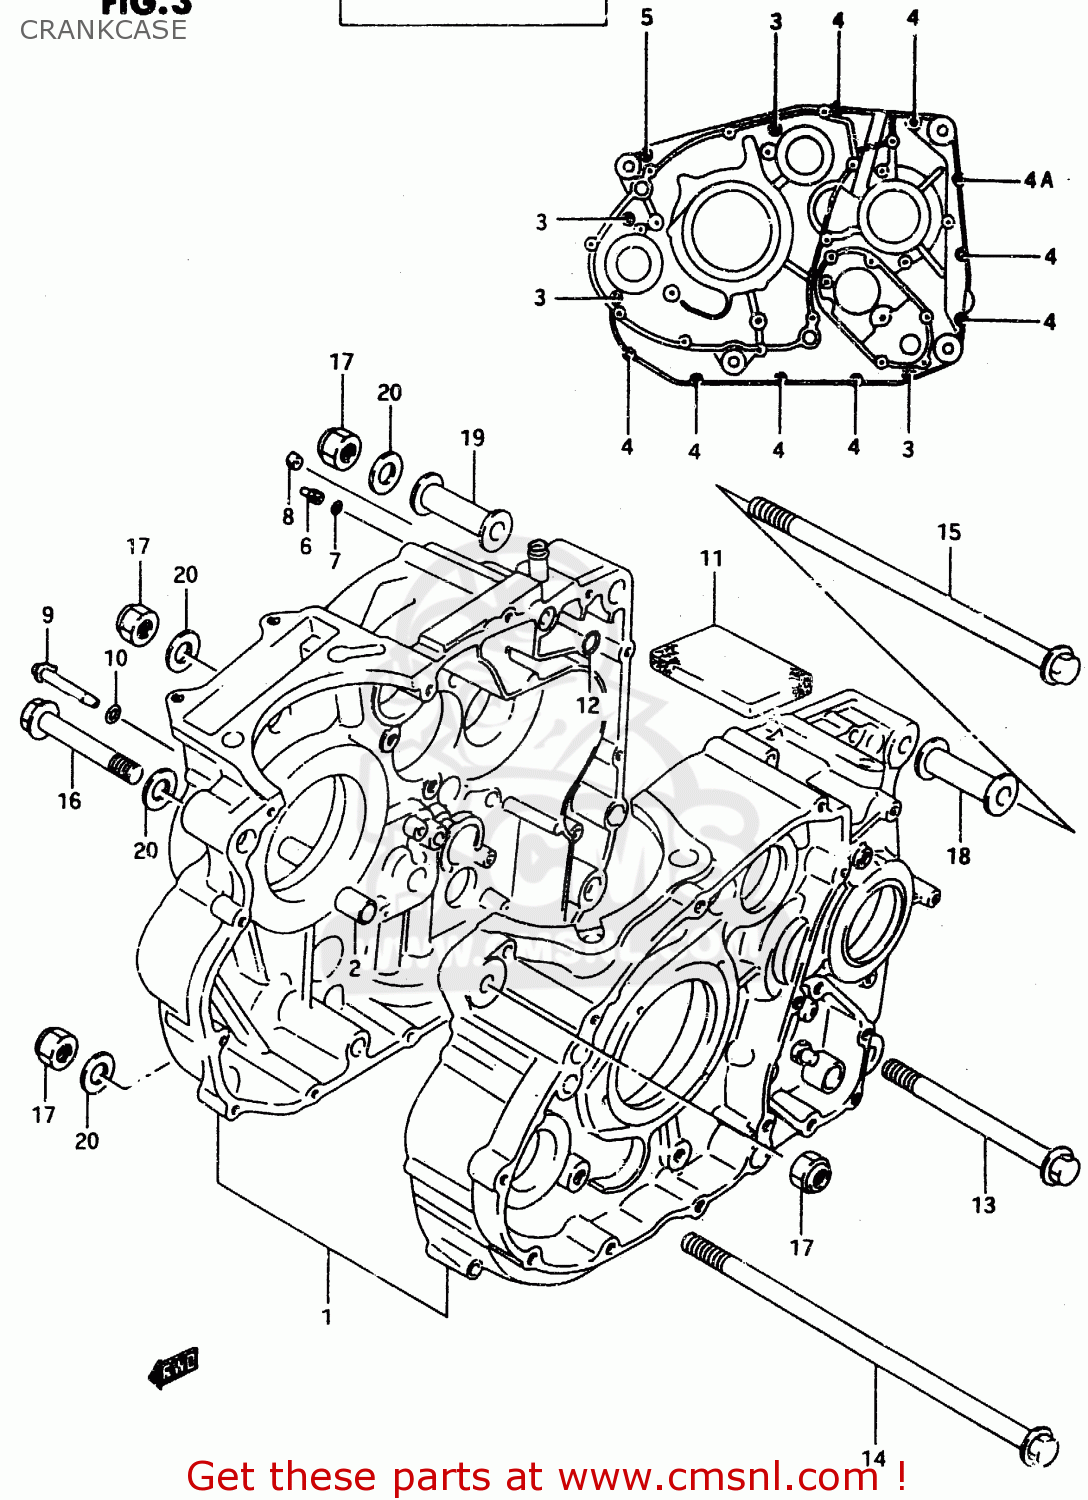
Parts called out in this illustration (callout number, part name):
1	CRANKCASE SET
2	PIN
3	BOLT
4	BOLT
4A	BOLT
5	BOLT,G/S SWITC
6	JET(12)
7	O RING(D:1.2,ID:4)
8	JET,OIL GALLERY
9	PIPE,PISTON COOLING
10	O RING(D:1.9,ID:7.8)
11	SEPARATOR,OIL BREATHER
12	O RING(D:1.9,ID:8.6)
13	BOLT(10X130)
14	BOLT 10X230
15	BOLT(10X235)
16	BOLT(10X80)
17	NUT
18	SPACER,ENG MTG(L:55)
19	SPACER,ENGINE MOUNT(L:65)
20	WASHER
